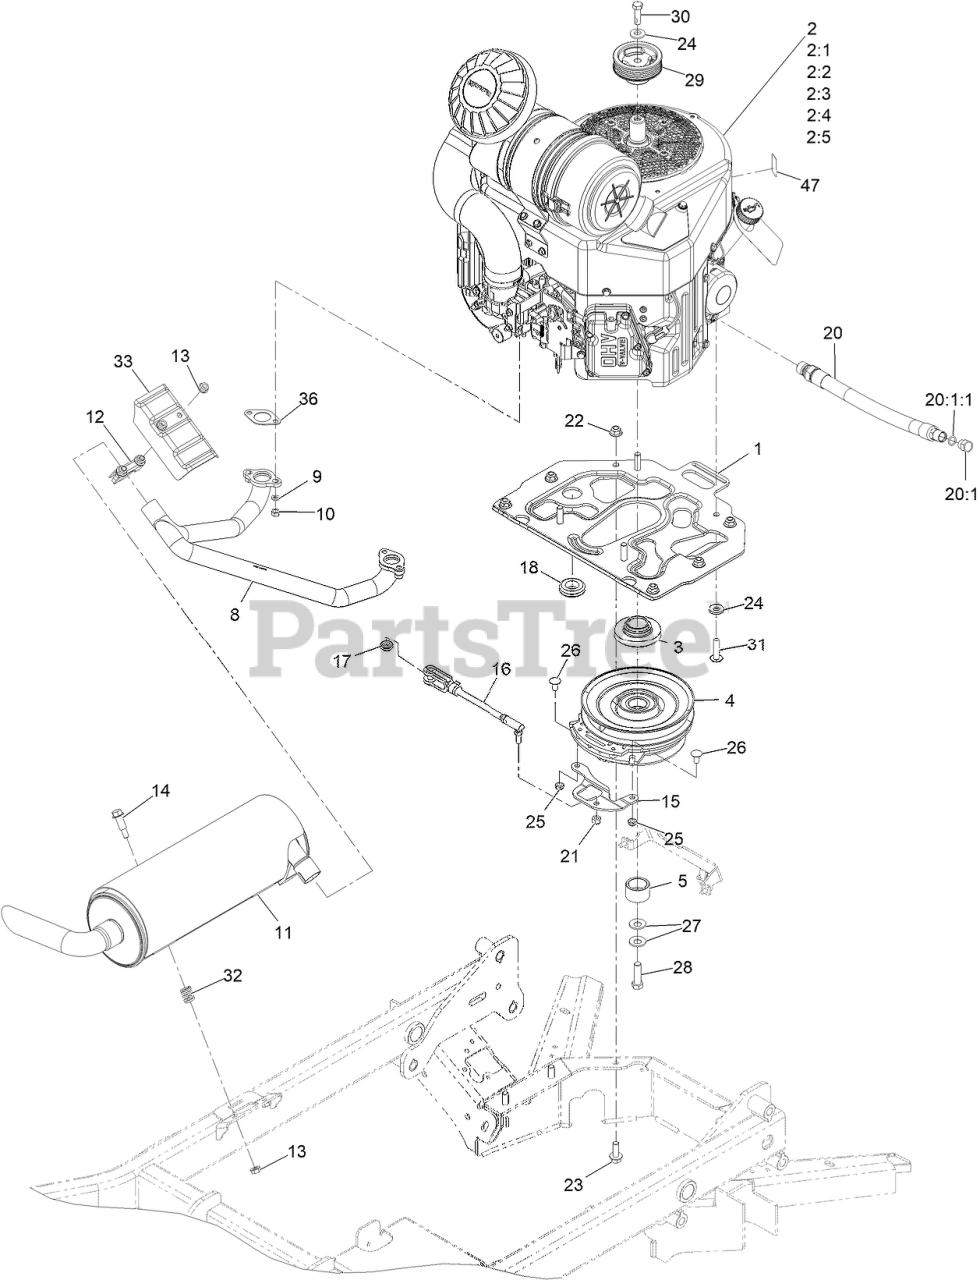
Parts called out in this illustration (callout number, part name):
1	PLATE, ENGINE
2:1	Kawasaki 49065-7007 Engine Oil Filter
2:2	Kawasaki 49019-0031 Fuel Filter
2:3	Kawasaki 92070-7004 Plug-Spark Bpr4ES
2:4	Kawasaki 11013-7045 Pre-Filter
2:5	Kawasaki 11013-7044 Air Filter
3	SPACER, CLUTCH 1.13
5	SPACER, CLUTCH
8	HEADER, KAWASWAKI
9	WASHER-LOCK
11	MUFFLER, 5
12	CLAMP-MUFFLER
14	Bolt-Shoulder
15	STRAP, CLUTCH
16	ASM, CLUTCH ANCHOR
17	GROMMET
18	GROMMET
20	ENGINE OIL DRAIN HOSE ASM
20:1	PLUG-HH
20:1:1	O-RING
21	NUT-LOCK
22	NUT-HF, NI
23	SCREW-HHF 3/8-16 X 1
24	WASHER-BELLEVILLE
25	NUT-LOCK, NI
26	SCREW-CARR
27	WASHER-SPRING
28	SCREW-HH 7/16-20 X 1 1/2 W/LOCTITE
29	PULLEY, CRANK
30	Screw-HH, Patch
31	SCREW-BHTF
32	SPRING, COMPRESSION
33	SHIELD, HEAT
36	GASKET-EXHAUST
47	DECAL-10W-50 OIL
